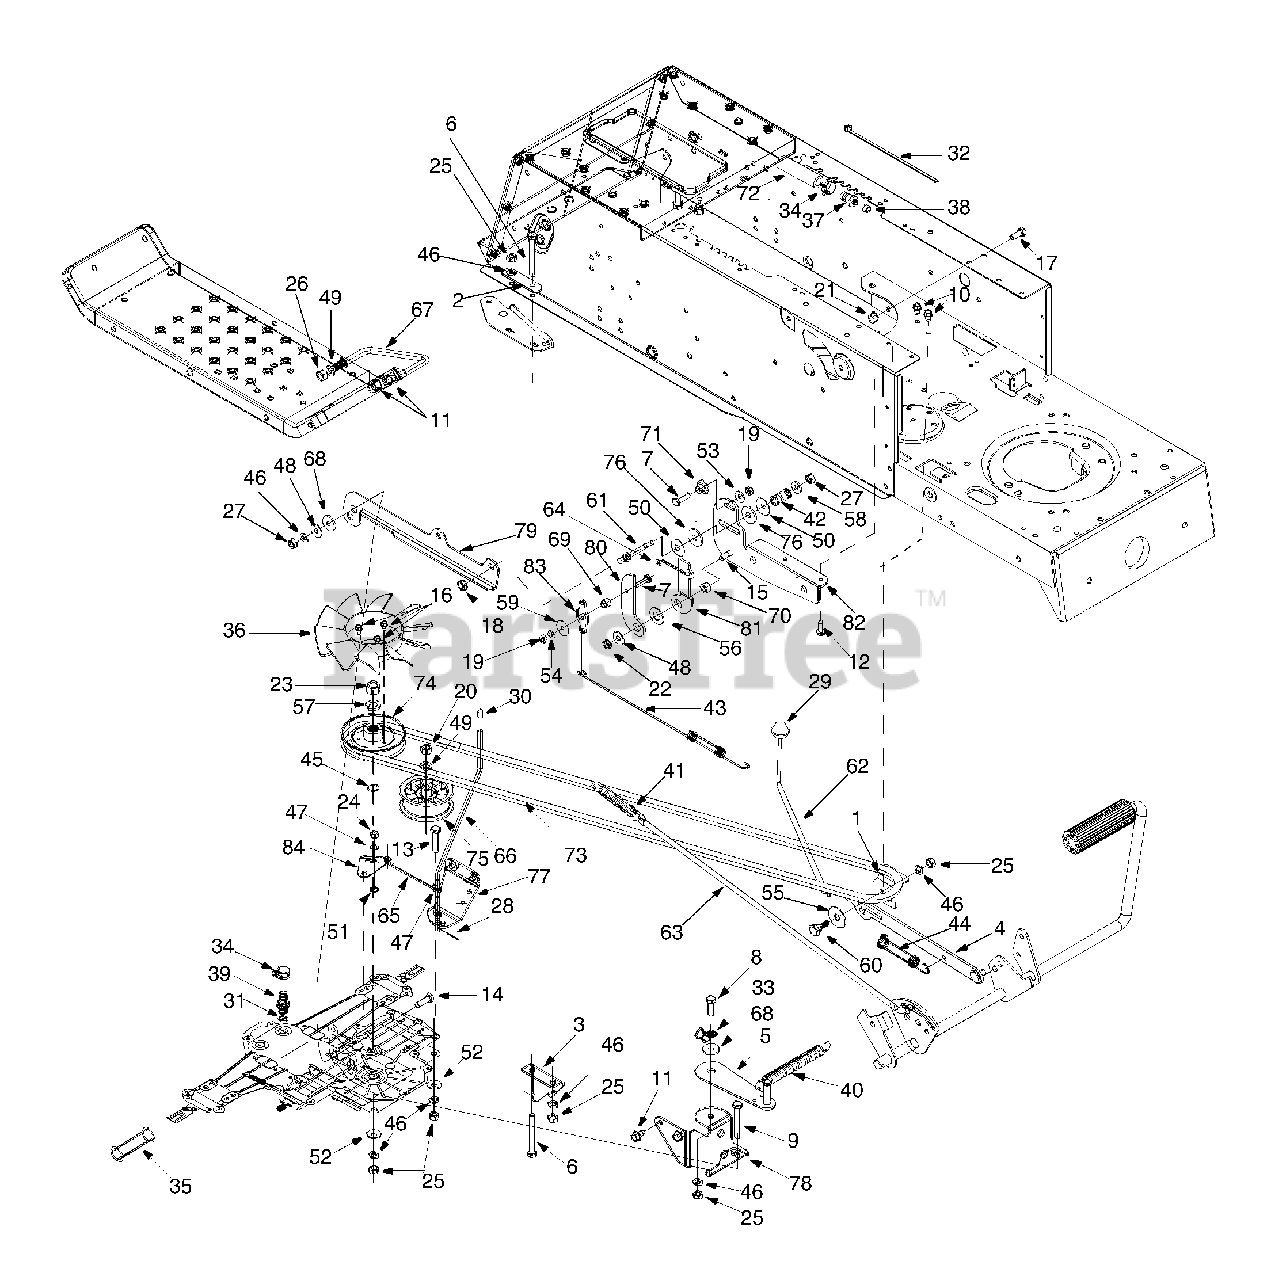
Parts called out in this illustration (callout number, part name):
1	Hydrostatic Bracket
7	Hex Screw 1/4-28 x 1.0" Special
8	Hex Screw 5/16-18 x 1.0"
9	Hex Screw 5/16-18 x 2.25"
10	TT Screw 1/4-20 x 0.5"
11	TT Screw 5/16-18 x 0.625"
12	TT Screw 1/4-20 x 0.75"
13	Hex Screw 5/16-18 x 1.5"
14	Hex Screw 5/16-24 x 1.0"
15	Hex Screw 5/16-18 x 1.0"
16	C Screw #12-24 x 0.375"
17	Hex Screw 5/16-18 x 0.75"
18	Jam Nut
19	Hex Nut 1/4-28
20	Hex Nut 3/8-24
21	Sems Nut
22	Hex Lock Nut 5/16-24
23	Hex Nut 1/2-20
24	Hex Nut
25	Hex Nut 5/16-18
26	Hex Nut 3/8-16
27	Hex Nut 5/16-24
28	Cotter Pin
30	Dipped Cap
31	O Ring
32	Cable Tie
33	Clamp
34	Fuel Clamp
35	Sleeve
36	Blade Fan
37	Plastic Vent
38	Plastic Vent Cap
39	Hose Fitting
40	Extension Spring
41	Extension Spring
42	Compression Spring
43	Neutral Return Spring
44	Extension Spring
45	Wire Ring
46	Lock Washer
47	Flat Washer
48	5/16 Washer
49	Lock Washer
50	Bell Washer
51	Lock Washer
52	Beleville Washer
53	Bell Washer
54	Lock Washer
55	Flat Washer
56	Flat Washer
57	Lock Washer
58	Flat Washer
59	Flat Washer
60	Shoulder Screw .437 x .286
61	Friction Disc Stud
62	Brake Lockout Rod
63	Brake Rod
64	Neutral Return Rod
65	Rod: Bypass Actuator
66	Lever: Bypass Control
67	Stop Pedal Rod
68	Shoulder Spacer
69	Shoulder Spacer
70	Spacer
71	Centering Gauge Spacer
72	Fuel Line
73	V Belt
74	Transmission Pulley
75	Flat Idler
76	Friction Washer
80	Flat Scissor
81	Offset Scissors
82	Mounting Bracket: Neutral Return
83	Lever: Neutral Return
84	Adjustment Bracket
